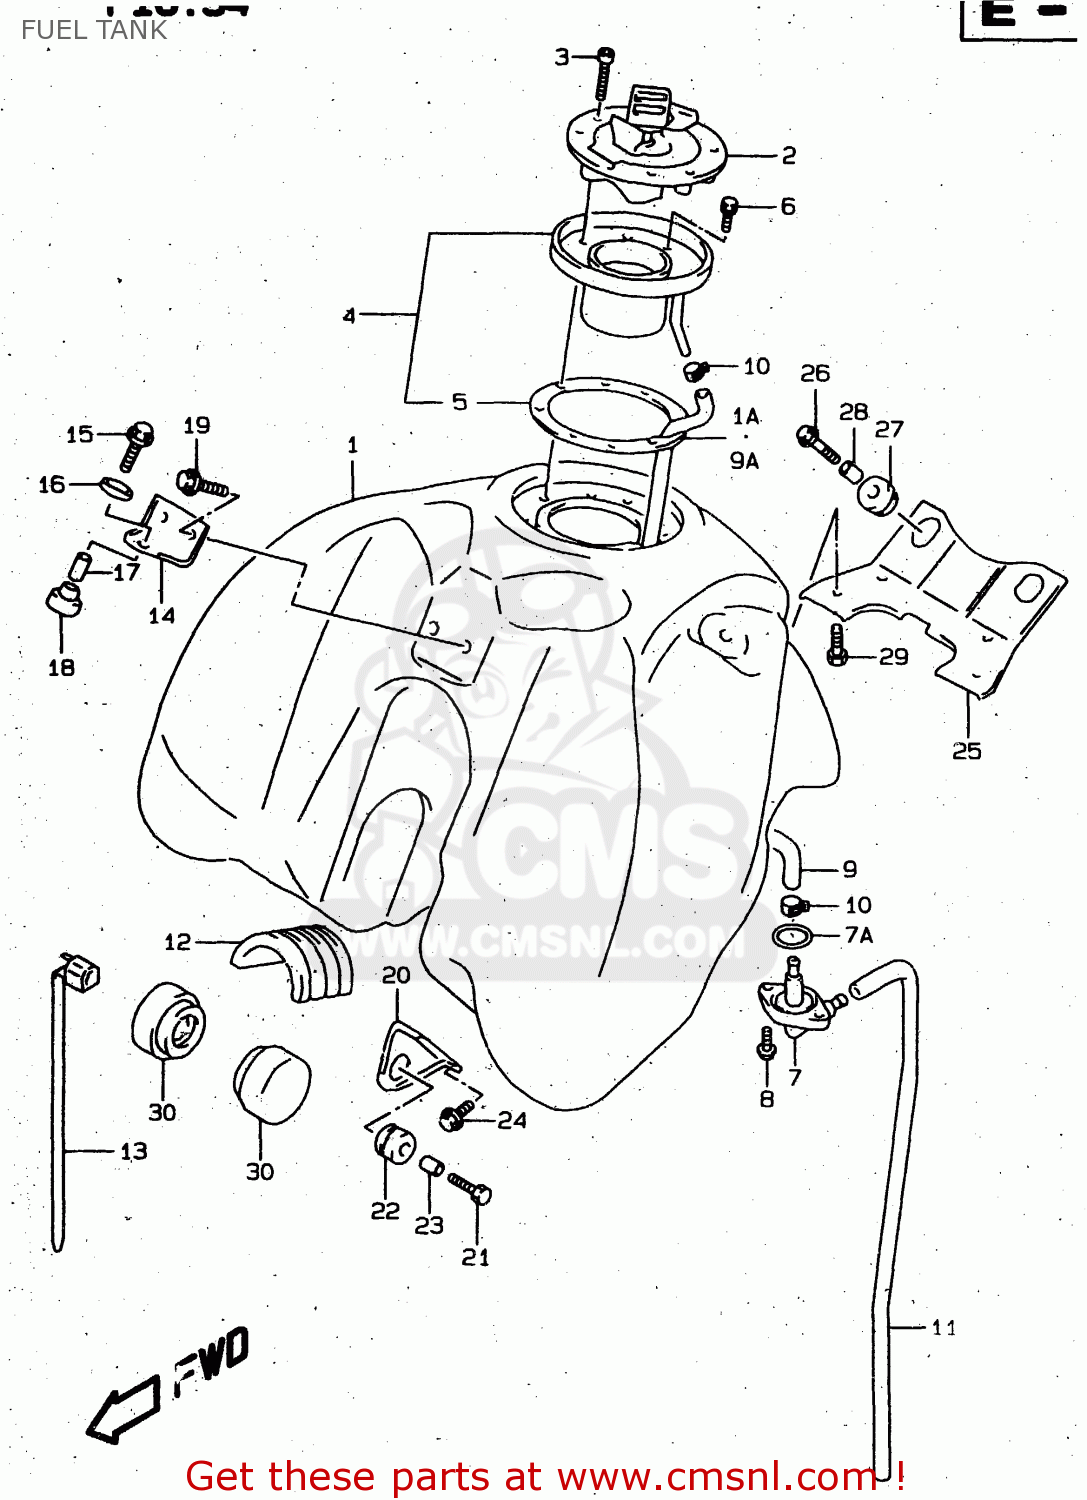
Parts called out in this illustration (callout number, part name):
1	TANK SET,FUEL
1A	PACKING,FUEL TANK,INLET (NAS)
2	CAP SET,FUEL TANK
3	BOLT, CAP
4	INLET SET,FUEL
5	PACKING,FUEL TANK,INLET (NAS)
6	BOLT 5X10
7	JOINT ASSY,FUEL TANK WATER DRN
7A	O RING,JOINT
8	SCREW
9	HOSE SET, INNER
9A	PACKING,FUEL TANK,INLET (NAS)
10	CLIP
11	HOSE,WATER DRAIN OUTER
12	CUSHION,FUEL TANK UPR
13	CLAMP(L:250)
14	BRACKET,FUEL TANK FR UPR
15	BOLT(6X30)
16	CUSHION,FUEL TANK RR
17	SPACER(6.5X9X18)
18	CUSHION
19	BOLT
20	BRACKET,FUEL TANK SIDE
21	BOLT(6X25)
22	CUSHION,FUEL TANK SIDE
23	SPACER(6.5X9X13.5)
24	BOLT
25	BRACKET,FUEL TANK RR
26	BOLT(6X25)
27	CUSHION,FUEL TANK SIDE
28	SPACER(6.5X9X13.5)
29	BOLT
30	CUSHION,FUEL TANK SIDE INNER
